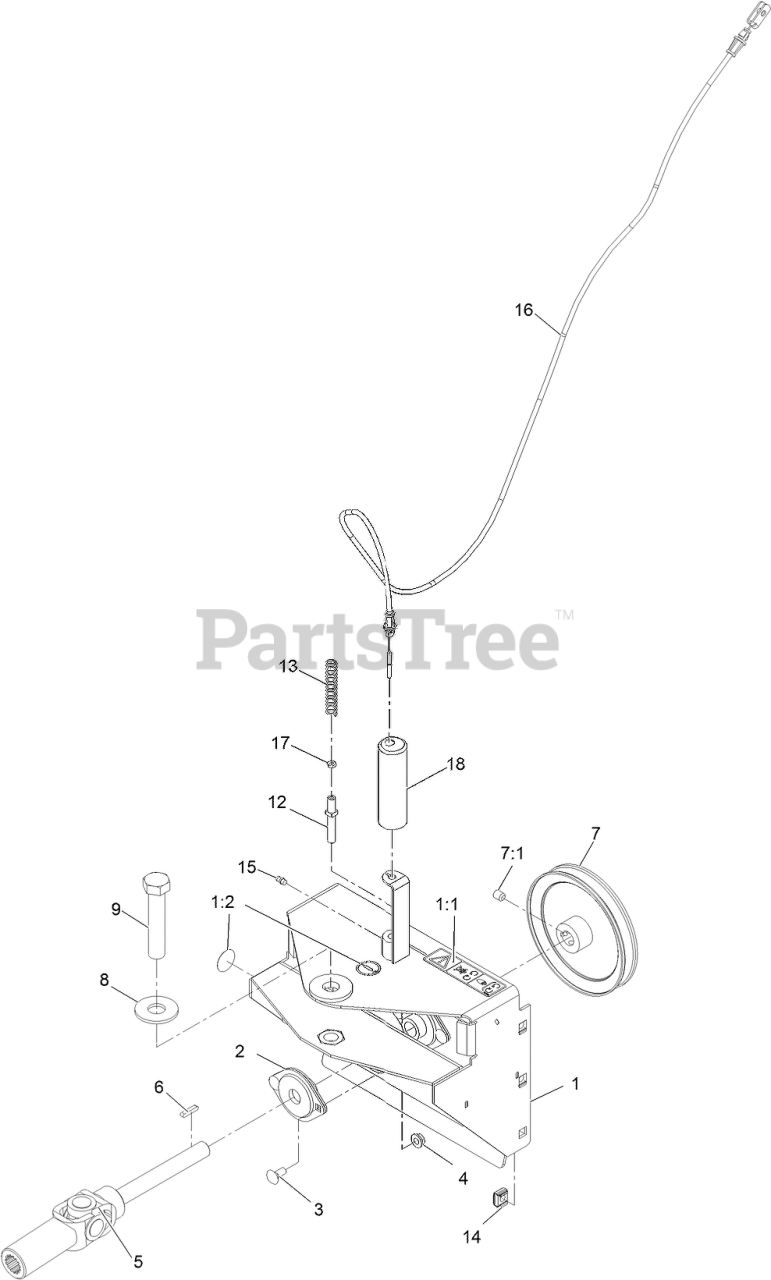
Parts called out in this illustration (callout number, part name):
1	BROOM MOUNTING FRAME ASM
1:1	DECAL-COVER, MISSING
1:2	DECAL-GREASE
2	BEARING-SHAFT
3	BOLT-CARR
5	SHAFT-DRIVE
6	KEY-ROUND END
7	PULLEY-IMPELLER
7:1	SETSCREW
8	WASHER-FLAT
9	SCREW-HH
12	PIN-SWING
13	SPRING-COMPRESSION
14	NUT-RETAINER
15	FITTING-GREASE
16	CABLE-ANGLE, BROOM
17	NUT-HEX
